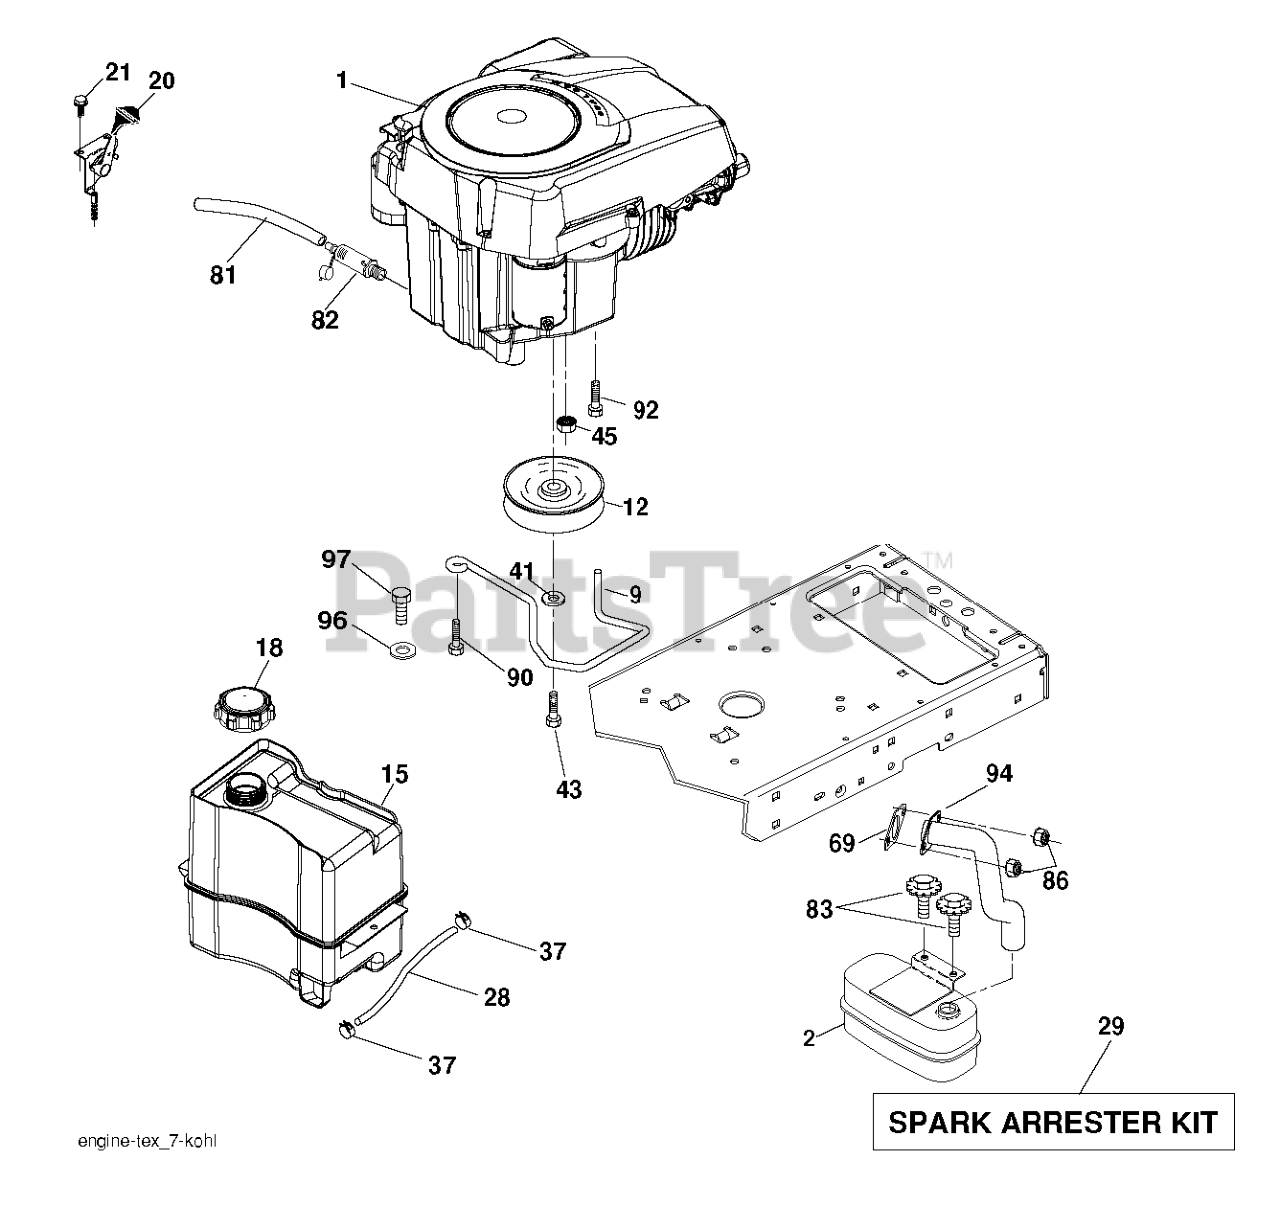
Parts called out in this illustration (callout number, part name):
2	MUFFLER.SINGLE.CYL.KOHL/B&S
9	KEEPER.BELT.ENGINE.3.25 (3 2)
12	PULLEY ENGINE
15	RP TANK FUEL FRT 1.5 GAL
18	FUEL CAP
20	CONTROL.TH/CK.C.
21	SCREW
28	LINE.FUEL.20
29	KIT.SPARK ARRESTOR 794945 B&S
37	HOSE CLAMP
41	LOCKWASHER
43	BOLT HEX 7/16-20X4-1/4"
45	NUT
69	Husqvarna TBD
81	TUBE, DRAIN OIL ASM.
82	PLUG DRAIN OIL EASY
83	BOLT.5/16-18UNCX3/4 W/SEMS.BLK
86	NUT.HEX.FLANGE.TOPLOCK
90	SCREW 3/8-16X1
92	SCREW 3/8-16X1
94	RP.TUBE.EXHAUST.KOHL.COURAGE
97	SCREW HEXWSHR 1/4-20X3/4
